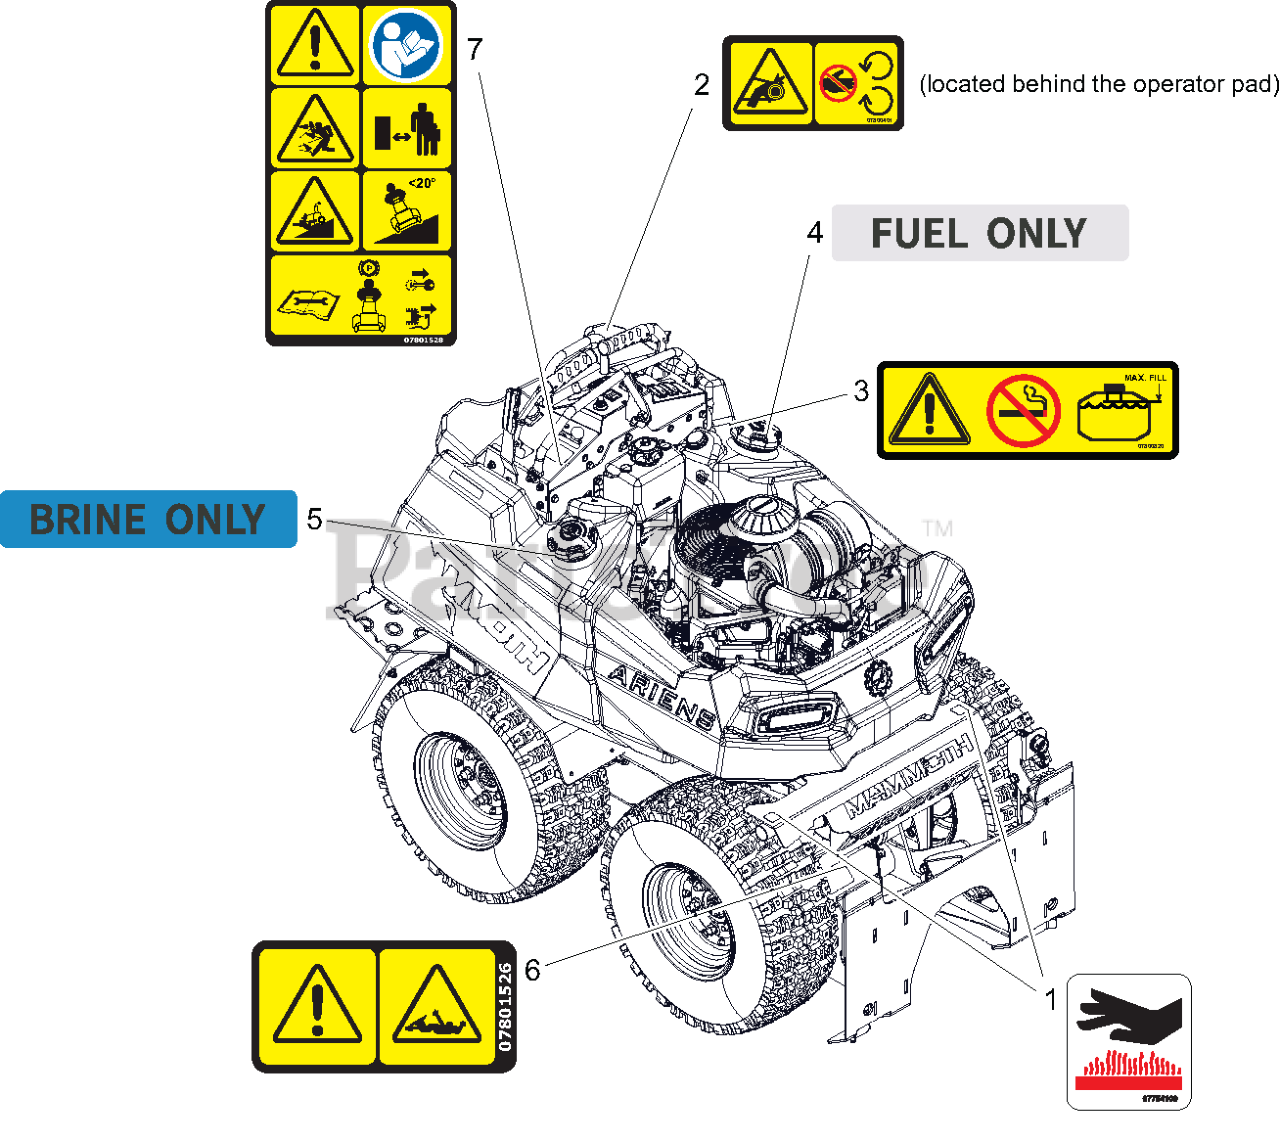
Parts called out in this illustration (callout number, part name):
1	DECAL, HOT SURFACE
2	DECAL, SAFETY - GUARDING
3	DECAL, FUEL WARNING
4	DECAL, TANK - FUEL
5	DECAL, TANK - BRINE
6	DECAL- SAFETY - ROTATING SHAFT
7	DECAL- SAFETY - DASH
